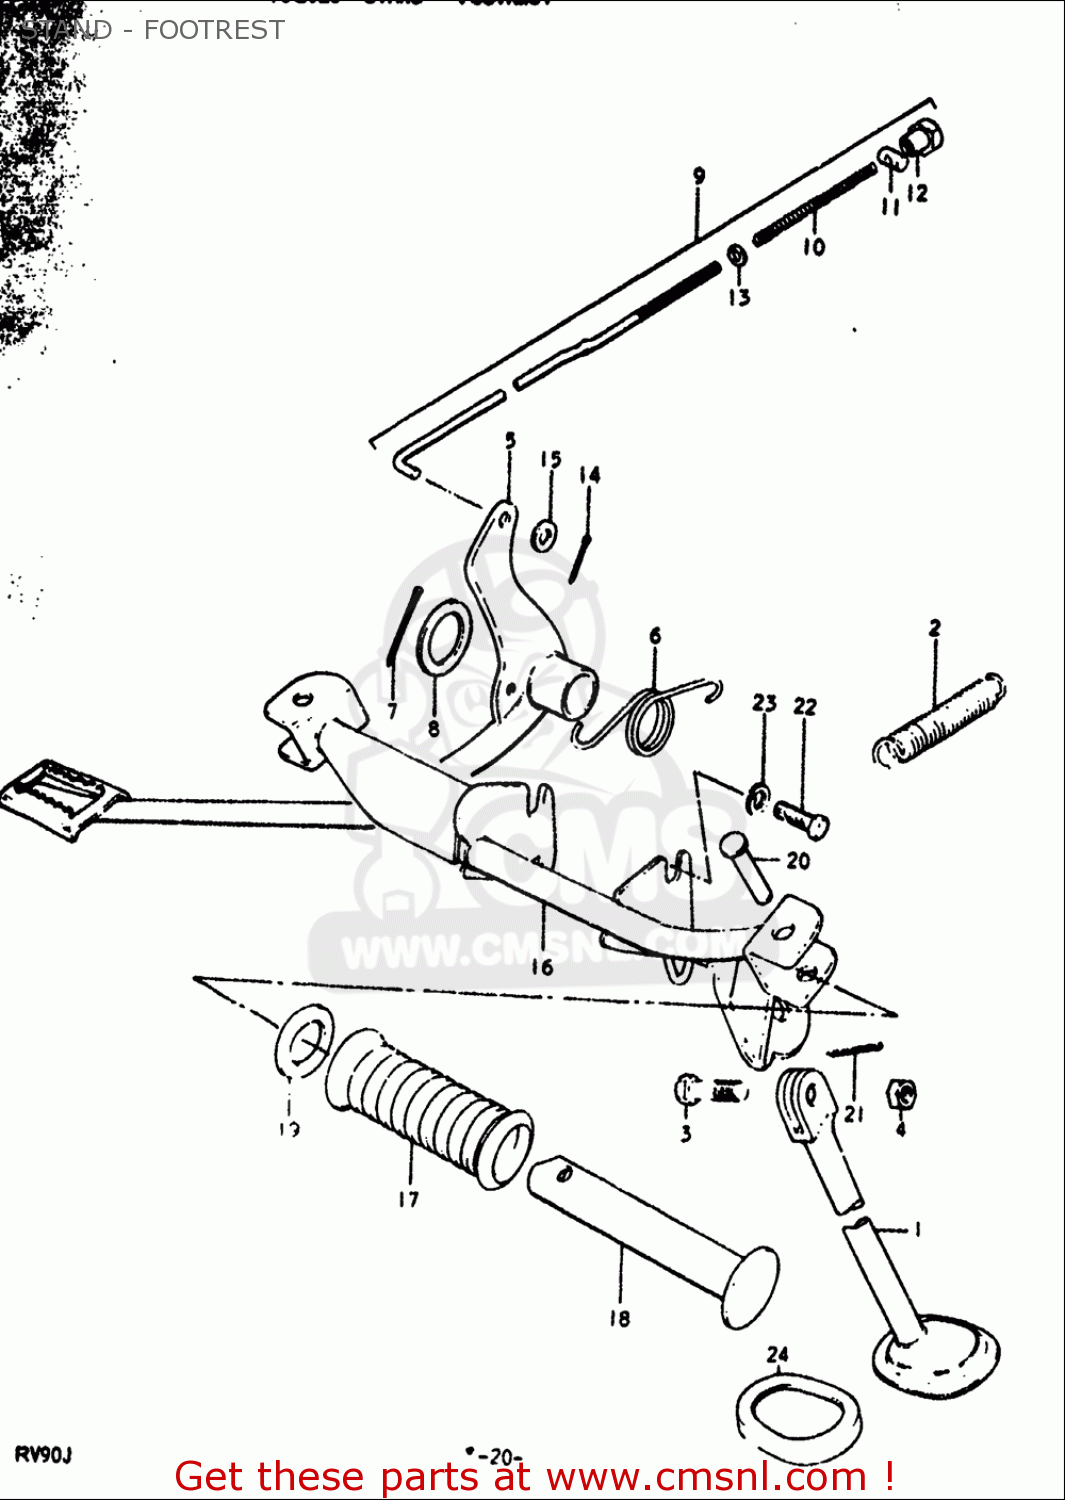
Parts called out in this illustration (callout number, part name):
2	SPRING
3	BOLT(10X30)
4	NUT
5	PEDAL,BRAKE
6	SPRING
7	PIN
8	WASHER(15.5X26X2.3)
9	ROD ASSEMBLY,REAR BRAKE
10	SPRING
11	PIN(11X18)
12	NUT
13	WASHER
14	PIN
15	WASHER
17	RUBBER,PILLION FOOTREST
18	BAR,FOOTREST RUBBER
19	WASHER(19.5X32X2)
20	PIN
21	PIN
22	BOLT
23	WASHER,LOCK
